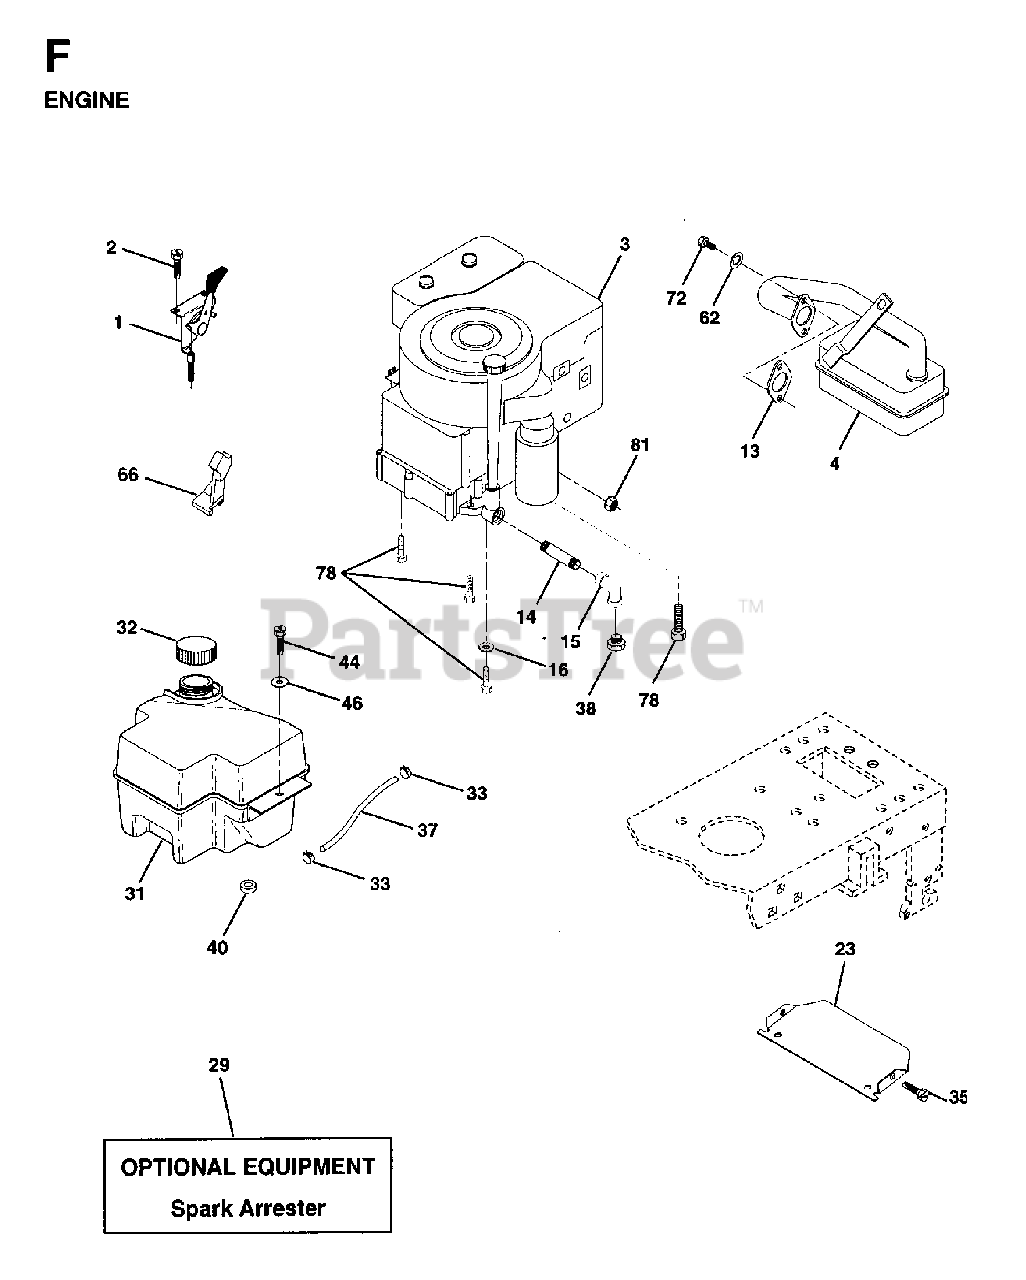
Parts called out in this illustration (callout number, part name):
1	CONTROL
2	SCREW LT
13	GASKET ENG
15	ELBOW
16	LOCKWASHER
23	SHIELD HEAT
29	ARRESTER SPARK (OPTIONAL)
31	FUEL TANK
32	FUEL CAP
33	HOSE CLAMP
35	SCREW
37	LINE.FUEL.20
40	GROMMET T
44	SCREW HEX CRT
62	LOCKWASHER
66	STOP THROTTLE
72	SCREW
78	SCREW
81	NUT FLANGE 1/4-20 STARTER NUT
